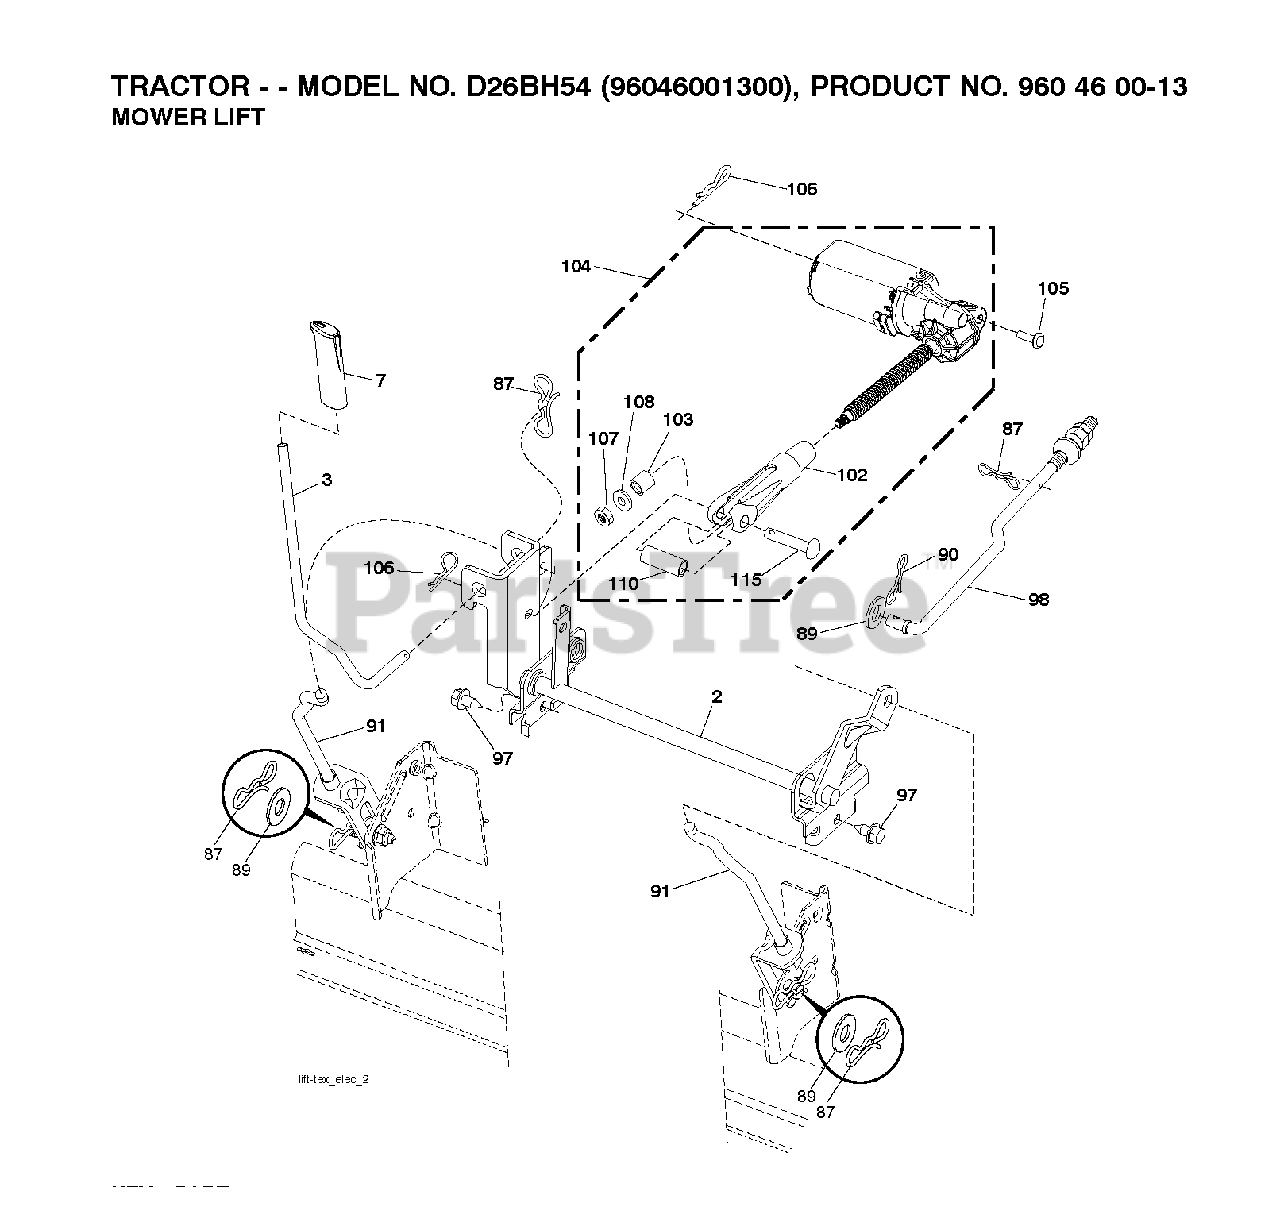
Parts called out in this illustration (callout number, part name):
2	SHAFT.ASM.CROSS.LIFT
3	ROD.INDICATOR.LIFT.ELECTRIC
7	CAP.INDICATOR.LIFT.ELECT.428
87	PIN.COTTER.7/16.BOW TI.
89	WASHER.CLEAR.ZINC
90	PIN.COTTER.5/16.BOW TI
91	LINK.ASM.LIFT.54"TG
97	SCREW, 3/8-16X3/4
98	LINK.ASM.SUSP.FRONT.MWR.10.5
102	CLEVIS.MOTOR.ELECTRIC
103	SPACER.TUBULAR
104	ACTUATOR.ASM.DECKLIFT.ELECT
105	RIVET,DRILLED
106	Retainer, M
107	NUT.SQ.1/4-20 UNC
110	SPACER.CLEVIS
115	PIN.CLEVIS.375X2.125
